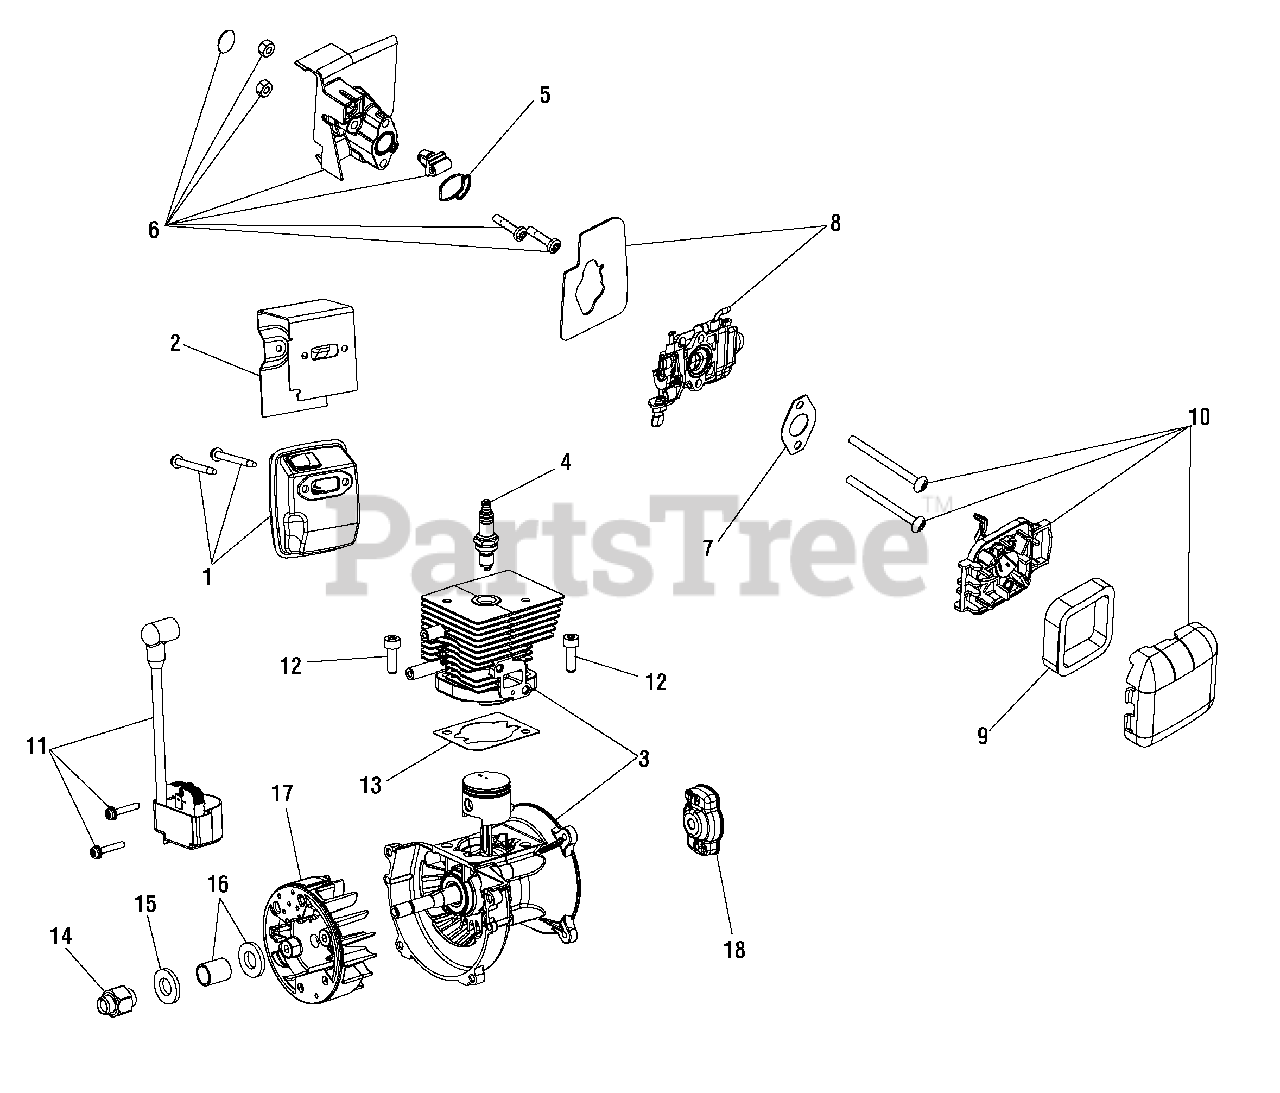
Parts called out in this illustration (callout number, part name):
1	Muffler Assembly
2	Muffler Gasket
3	Shortblock Assembly
4	Spark Plug
5	Insulator O-Ring
6	Insulator Assembly
7	Carburetor Gasket
8	Carburetor Assembly
9	Air Filter
10	Air Cleaner Assembly
11	Module Assembly
12	Screw
13	Cylinder Gasket
14	Flywheel Adaptor
15	Washer
16	Bushing
17	Flywheel Assembly
18	Pawl Assembly
